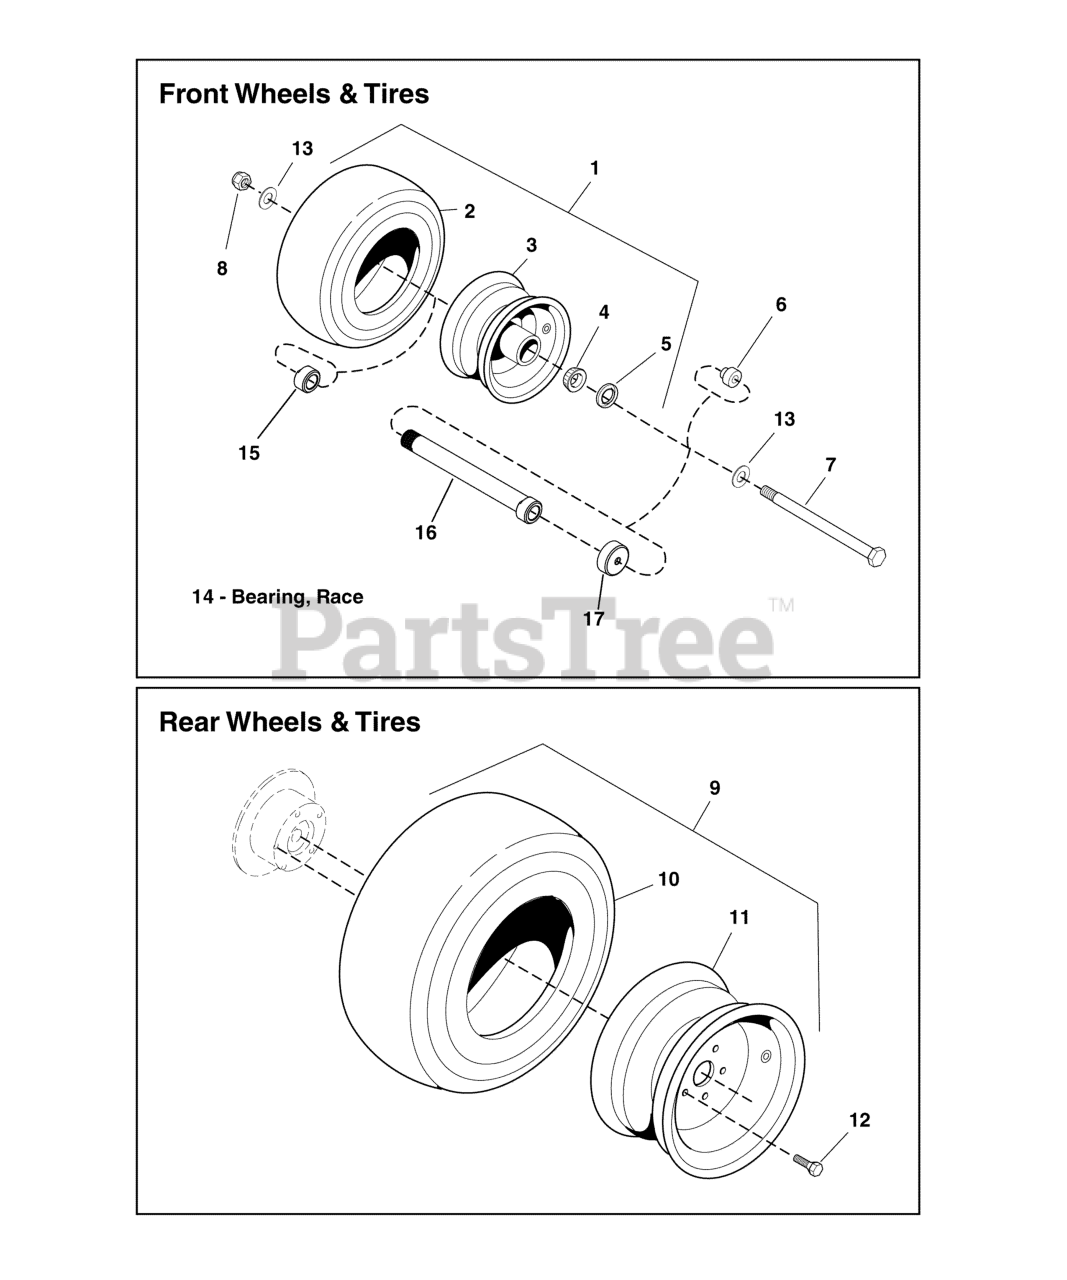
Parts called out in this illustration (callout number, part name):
1	TIRE ASSM, 13 X 6.5 - 6, PNE / TB
2	TIRE, RUBBER ONLY
3	WHEEL ASSEMBLY, FOR 13 X 6.5 X 6 TIRES (INCLUDES BEARING AND SEALS)
4	BEARING, Tapered Roller
5	SEAL, GREASE
6	ADAPTER, CASTER AXLE, CZ
7	BOLT, 1/2-13 X 9" GD5 YZ
8	NUT, 1/2-13 HEX NYLON LOCK
9	TIRE WHEEL ASM, 24X12.00-12, TURF MASTER
9	TIRE/WHEEL ASM, 24 X 12.00-12, TURF SMART
10	TIRE, 24 X 12 X 12
10	TIRE, 24X12.00-12, TURF SMART
11	WHEEL, 12 X 8.5
12	BOLT, WHEEL LUG, 1/2" X 1-5/8
13	WASHER, 1/2 SAE
15	NUT, BEARING ADJUSTER, AXLE
16	BEARING ADJUSTER, SPACER, 7.062 LG
17	DEBRIS, COVER, CASTER WHEELS
